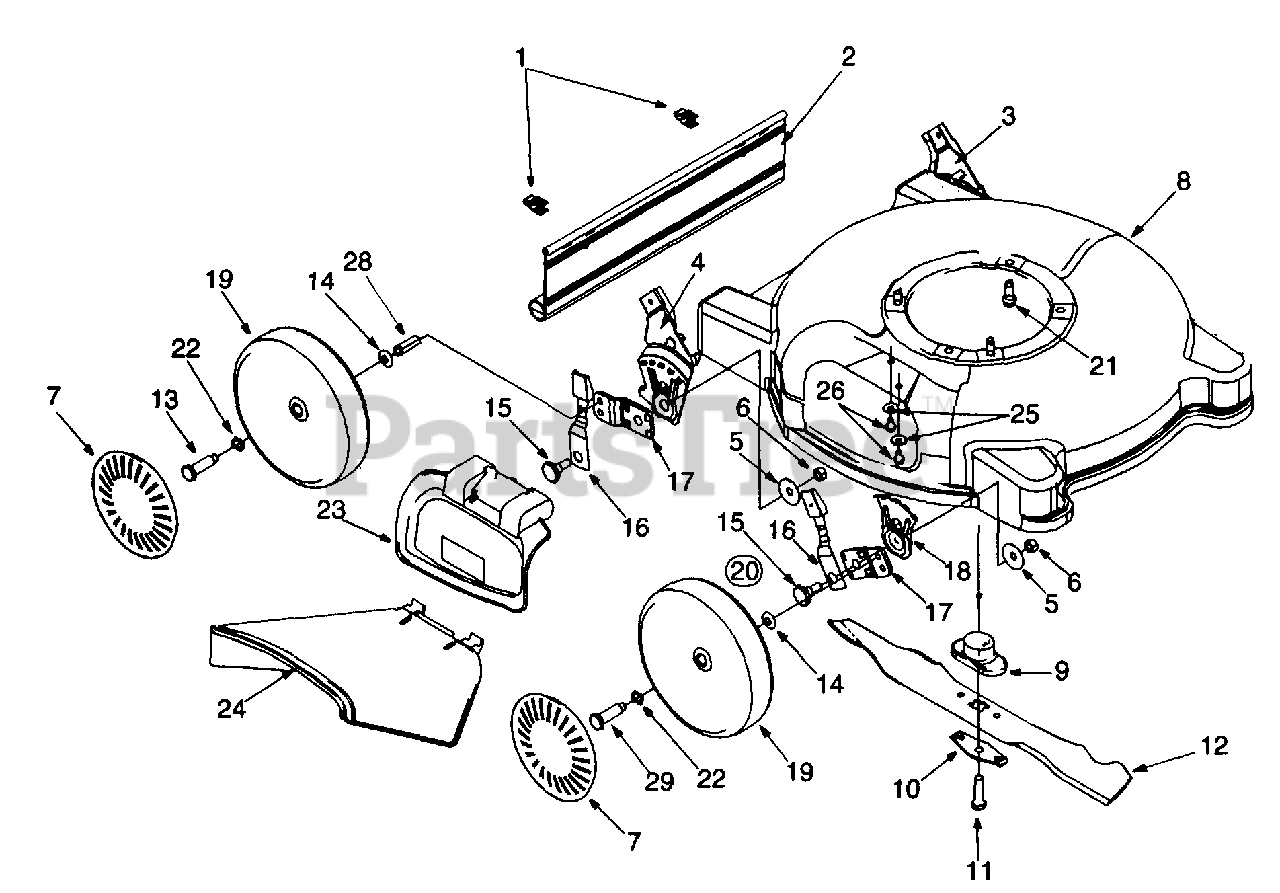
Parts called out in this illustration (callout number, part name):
1	Hinge Clip
2	Rear Flap
3	Handle Bracket Ass'y LH
4	Handle Bracket Ass'y RH
5	Bell Washer .39" ID x 1.38"
6	Hex Nut 3/8-16 Thd.
7	Hub Cap: Beige
10	Blade Bell Support
11	Hex Bolt 7/16-20 x 1.5"
12	18" Mulch Blade
13	Axle Bolt
14	Bell Washer .400" ID x .88"
15	Shoulder Bolt
16	Spring Lever Ass'y w/Knob
18	Height Adj. Plate
19	Wheel Assembly
20	Height Adj. Ass'y. Comp. R.F.
21	Hex Lock Wash. Hd. Screw 3/8-16 x 1.0" Lg.
22	Wave Washer
23	Mulching Plug
24	Chute Deflector
25	Bell Washer
26	Hex Wash. Hd. TT Screw 1/4-20 x .5" Lg.
28	Spacer
29	Axle Bolt
